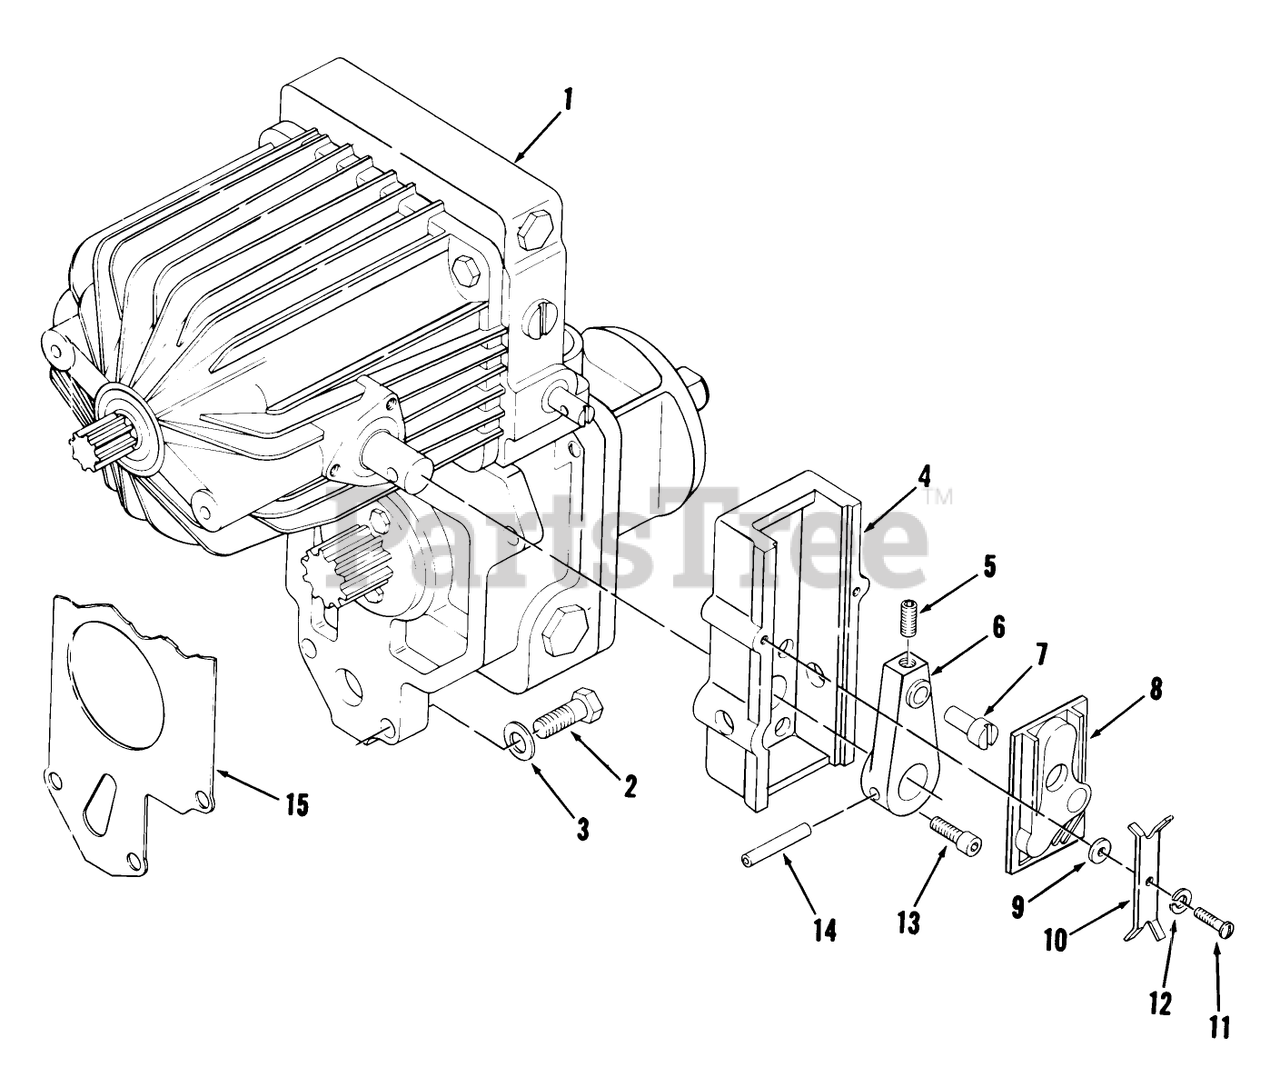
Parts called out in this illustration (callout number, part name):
1	SER BULLT 437B
8	CAM
15	GASKET
